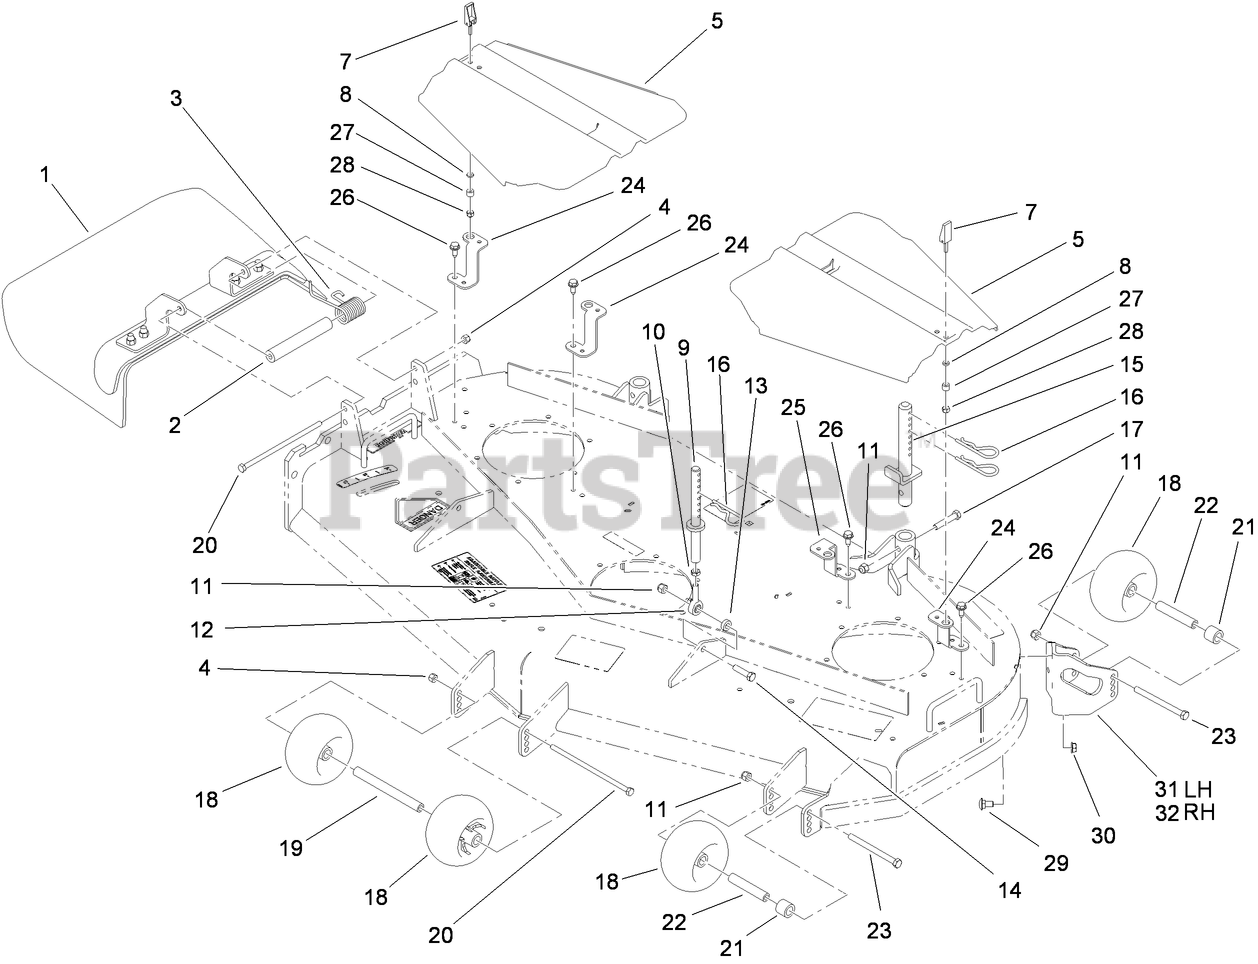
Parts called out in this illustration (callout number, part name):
1	DEFLECTOR ASM
2	SPACER
3	SPRING-TORSION
4	NUT-LOCK, NI
5	COVER-BELT
7	HANDLE-LATCH, SWELL
8	WASHER
9	FRONT PIN ASM
10	NUT-HJ
11	NUT-LOCK, NI
12	BALLJOINT
13	SPACER
14	SCREW-HH
15	REAR PIN ASM
16	PIN-HAIR
17	SCREW-HH
18	ROLLER-SCALP, ANTI
19	SPACER-WHEEL
20	SCREW-HH
21	TUBE-SPACER
22	TUBE-SPANNER
23	SCREW-HH
24	BRACKET-COVER
25	BRACKET-COVER
26	SCREW-HWHTF
27	BUSHING-LATCH, SWELL
28	NUT-LOCK, HH
29	SCREW-CARR
30	NUT-HF
31	BRACKET-ROLLER, LH
32	BRACKET-ROLLER, RH
